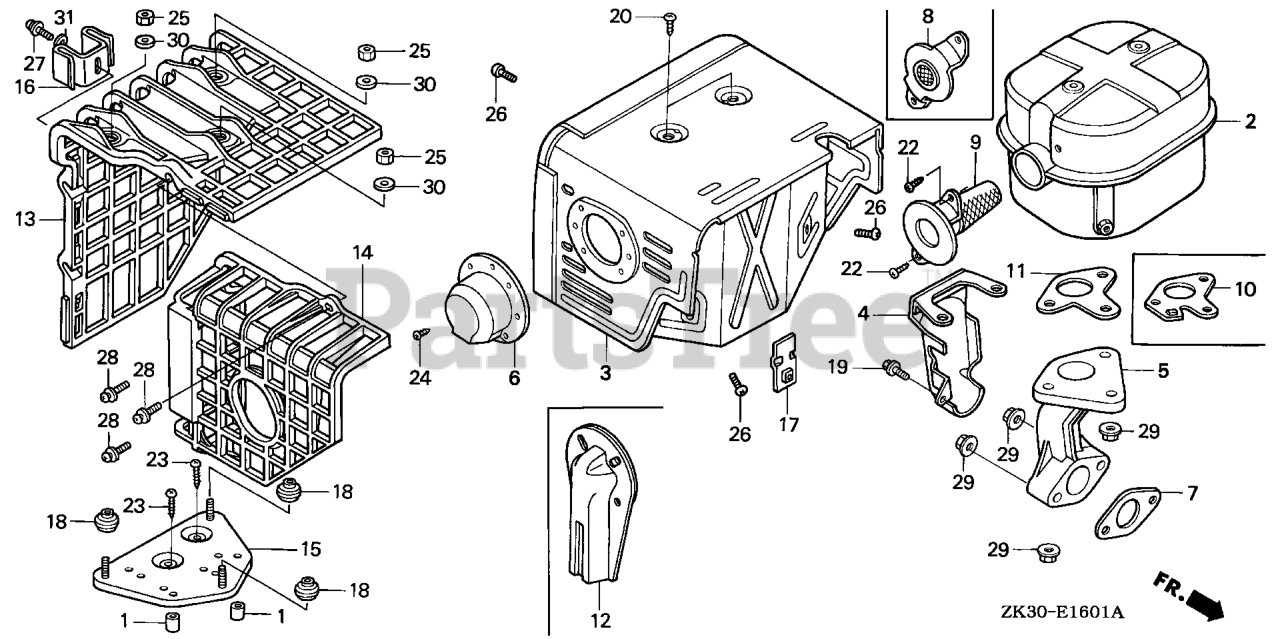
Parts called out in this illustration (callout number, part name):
3	PROTECTOR, MUFFLER
4	PROTECTOR, EX. PIPE
6	CAP, MUFFLER
7	GASKET, EX. PIPE Use up to Engine SN 2949254.
7	GASKET, EX. PIPE (WACKER)
7	GASKET, EX. PIPE
8	FLANGE, BAFFLE
9	ARRESTER, SPARK
11	GASKET, MUFFLER
11	GASKET, MUFFLER (NIPPON LEAKLESS)
19	BOLT, FLANGE (6X12) (CT200)
20	SCREW, TAPPING (5X8)
24	SCREW, TAPPING (4X6) (TO INSTALL OPTIONAL SPARK ARRESTER)
26	SCREW, PAN (6X6)
29	NUT, FLANGE (8MM)
